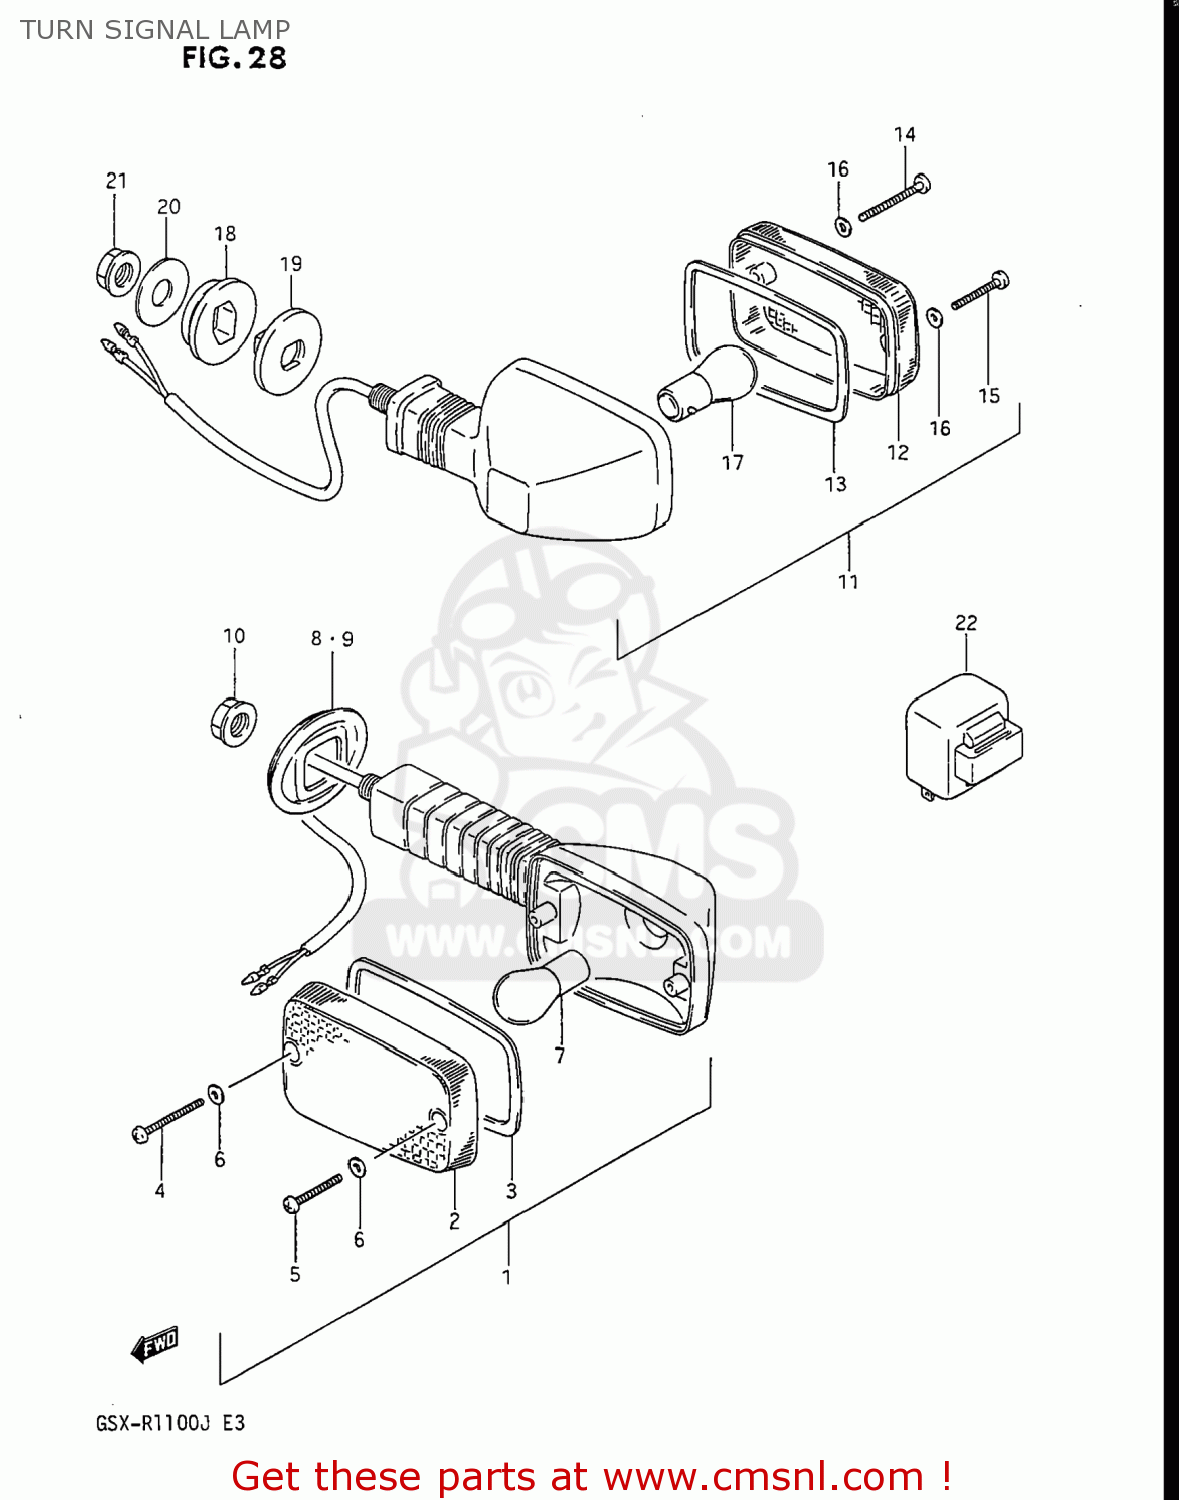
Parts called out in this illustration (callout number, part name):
1	LAMP ASSEMBLY,FRONT TURN SIGNAL
2	LENS,FR
3	GASKET (NAS)
4	SCREW,TURN SIG LENS FITTING
5	SCREW
6	GASKET (NAS)
7	BULB(12V23W,STANLEY,A4577A)
8	GROMMET,TURNSIGNAL LAMP,R
9	GROMMET,TURNSIGNAL LAMP,L
10	NUT
11	LAMP ASSEMBLY,REAR TURN SIGNAL
12	LENS,RR
13	GASKET (NAS)
14	SCREW,TURN SIG LENS FITTING
15	SCREW
16	GASKET (NAS)
17	BULB(12V23W,STANLEY,A4577A)
18	CUSHION
19	SPACER
20	WASHER (10.2X27X1.6)
21	NUT
22	RELAY ASSEMBLY,TURN SIGNAL
